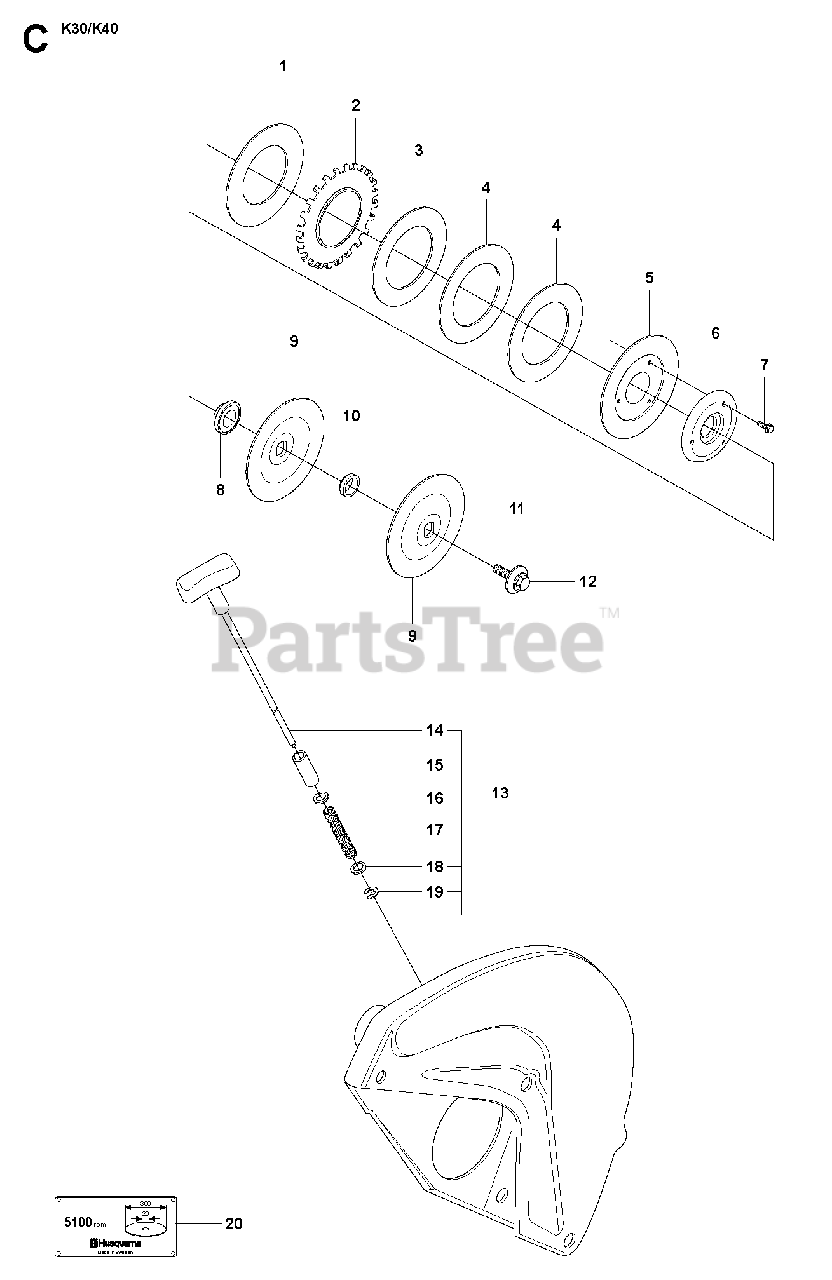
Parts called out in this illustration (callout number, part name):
5	SPRING WASHER
8	SUPPORT FLANGE
9	FLANGE WASHER
10	BUSHINGDiam 30,5mm
10	KITDiam 20mm
10	KITDiam 22,2mm
10	KITDiam 25mm
13	WHEEL GUARD ASSYIncl. 14 - 19
